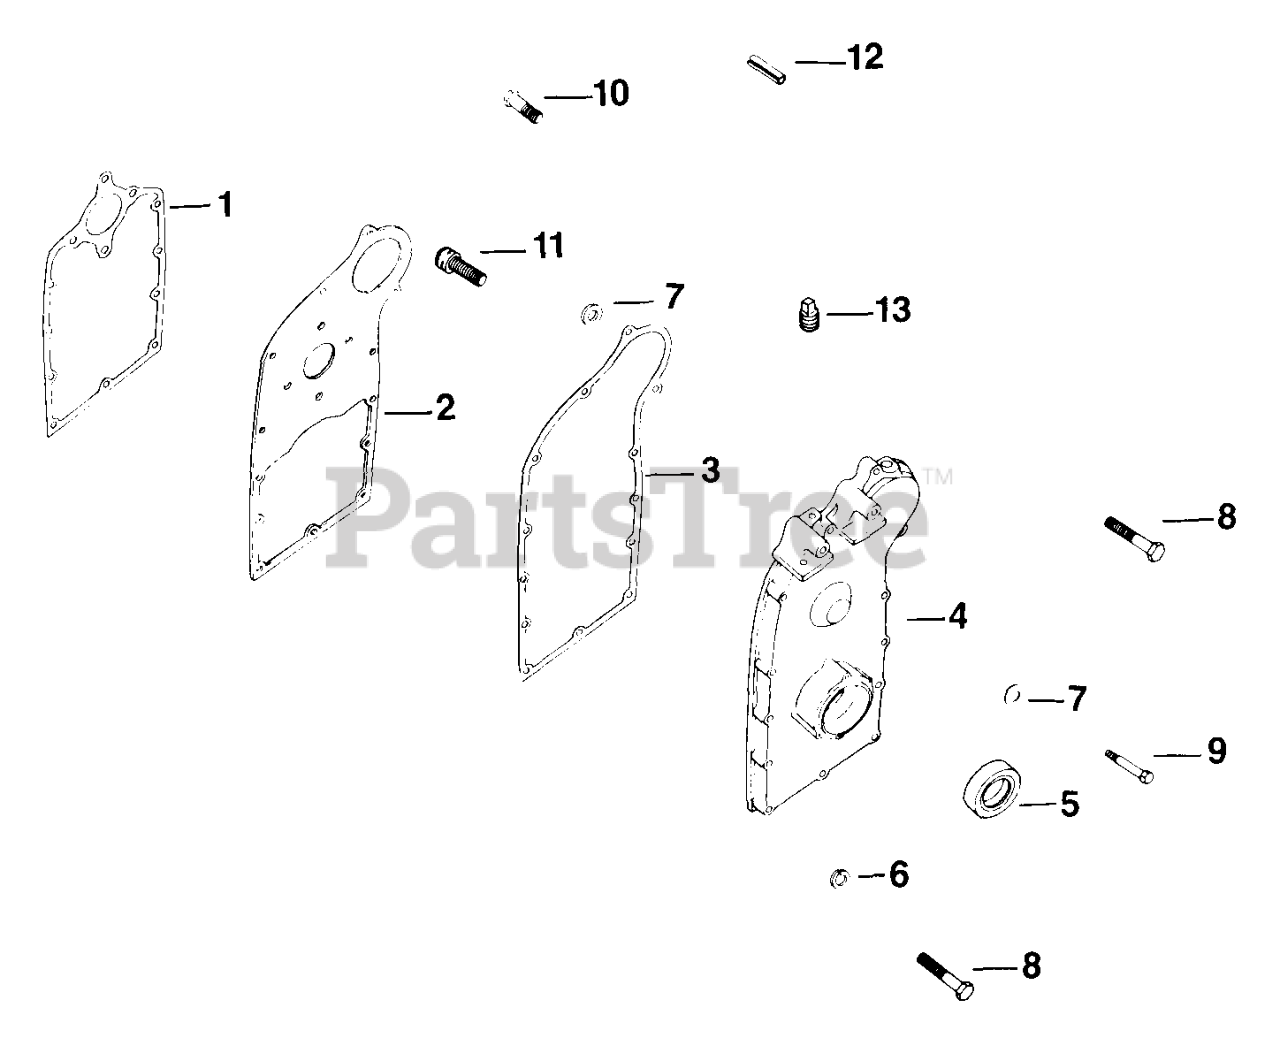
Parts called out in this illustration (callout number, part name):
2	PLATE - (#DSC)
5	SEAL, OIL (KM)-USE 25 032 06-S
6	WASHER, SPRING LOCK 5/16"
8	SCREW, CAP HD 5/16-18x1 3/4"- (#DSC)
9	SCREW - (#DSC)
10	SCREW, CAP HD 5/16-18x3/4"
11	SCREW, HEX SOCKET HEAD CAP USE 25 086 87-S
13	PLUG,PIPE 1/4 NPTF SQUARE HD USE 25 139 53-S
